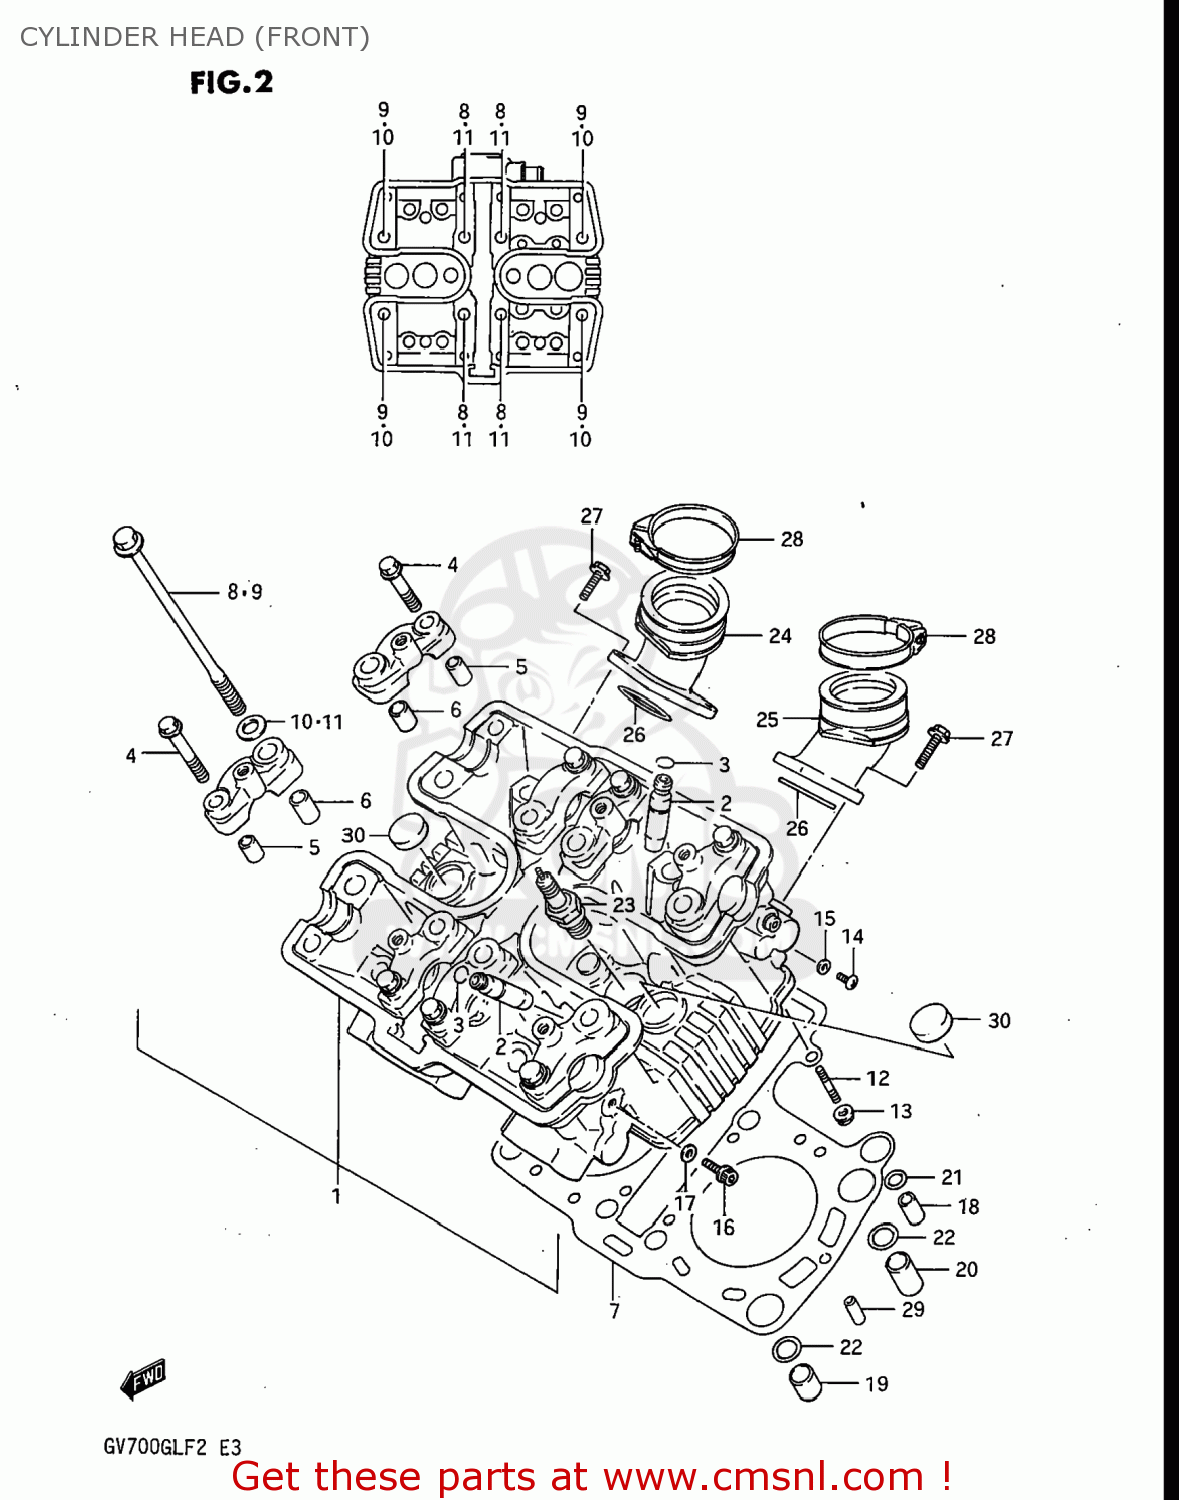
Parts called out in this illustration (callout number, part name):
1	HEAD ASSEMBLY,CYLINDER,FRONT
2	GUIDE,VALVE
3	RING,SNAP
4	BOLT
5	PIN (11X20)(SUS)
6	PIN(10.4X13X22)
7	GASKET,CYLINDER HEAD (MCA)
8	BOLT
9	BOLT
10	WASHER
11	WASHER (10X20X2.3)
12	STUD 6X25
13	NUT 6MM
14	SCREW
15	GASKET(5.3X9.3X1.2) (NAS)
16	BOLT
17	GASKET(6.2X13X1.2) (NAS)
18	PIN(6.4X9X20)
19	PIN
20	PIN
21	O RING(D:1.9,ID:8.6)
22	O RING(D:1.9,ID:12.6)
23	SPARK PLUG D8EA
24	PIPE,INTAKE
25	PIPE,INTAKE
26	O RING(D:2.4,ID:35)
27	BOLT
28	CLAMP,PIPE
29	PIN
30	PLUG
